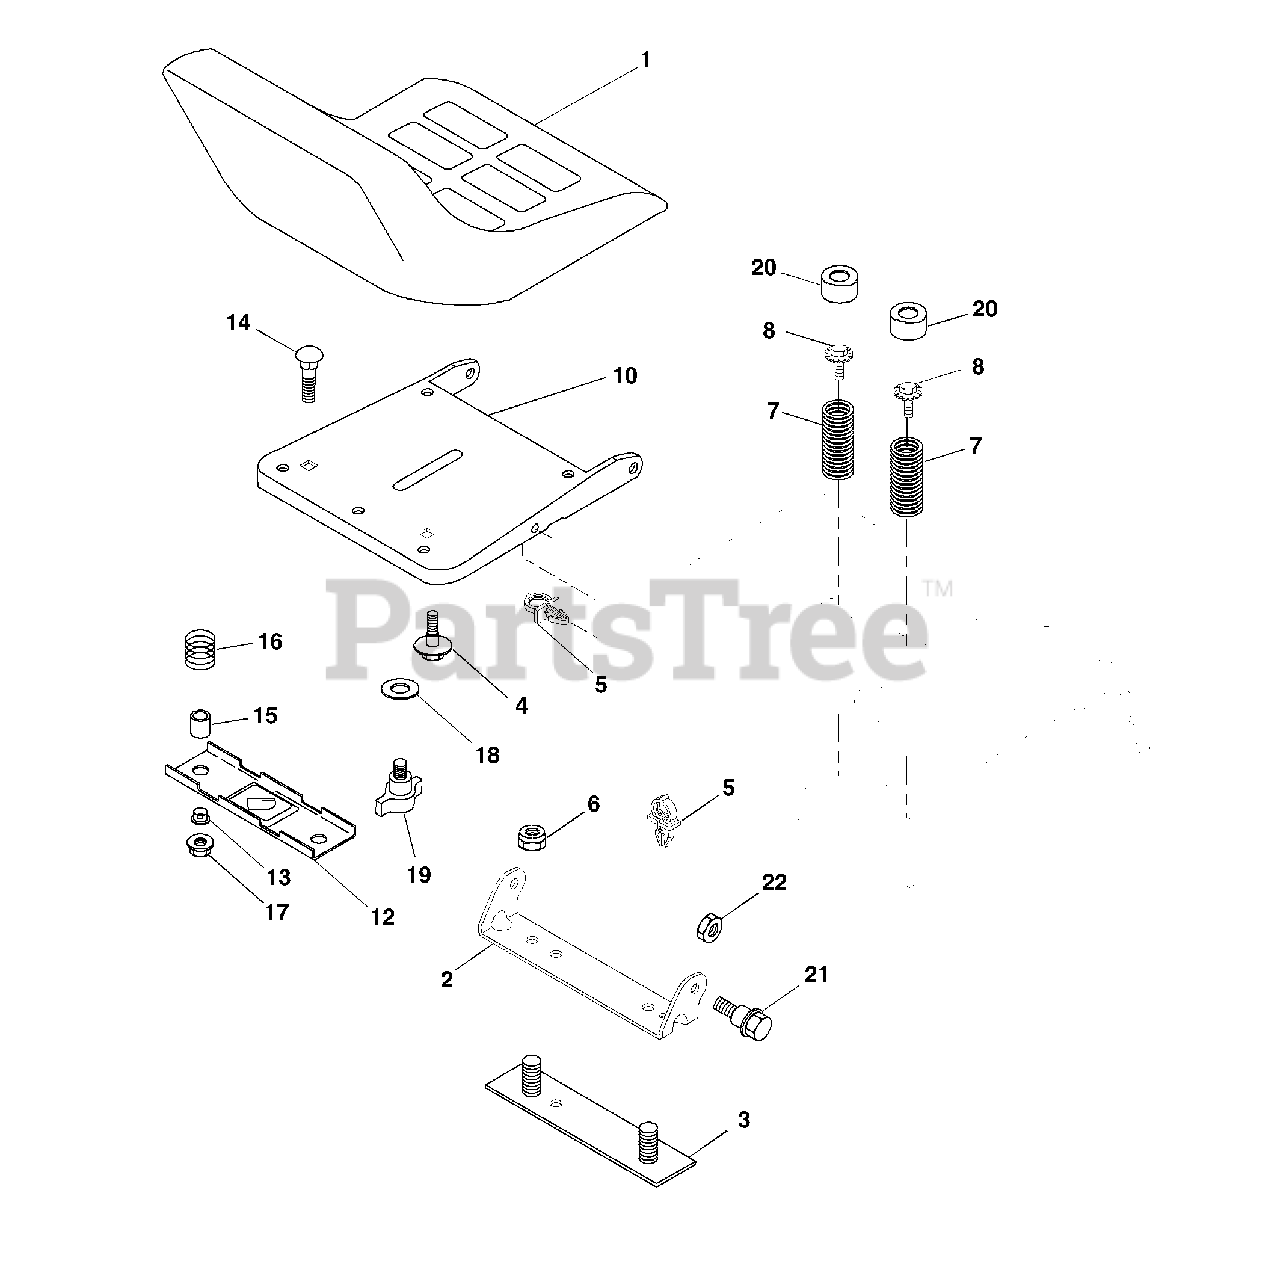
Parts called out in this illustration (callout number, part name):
1	Seat
2	Bracket, Pivot Seat
3	Strap, Fender
4	Bolt, Shoulder 5/16-18 X .62
5	Clip, Push In Hinged
6	Nut, Crownlock 3/8-16
7	Spring, Seat Cprsn
8	Bolt 5/16-18 UNC X 3/4
10	Pan, Seat
12	Bracket, Mounting Switch
13	Bushing, Snap
14	Bolt, Carriage 1/4-20 X 1-1/2
15	Spacer, Split
16	Spring, Cprsn
17	Nut, Lock 1/4 Lge Flg Gr. 5
18	Washer 17/32 X 1-3/16 X 12 Ga.
19	Knob, Seat
20	Cap, Spring Seat
21	Bolt, Shoulder 5/16-18
22	Nut, Crownlock 5/16-18
